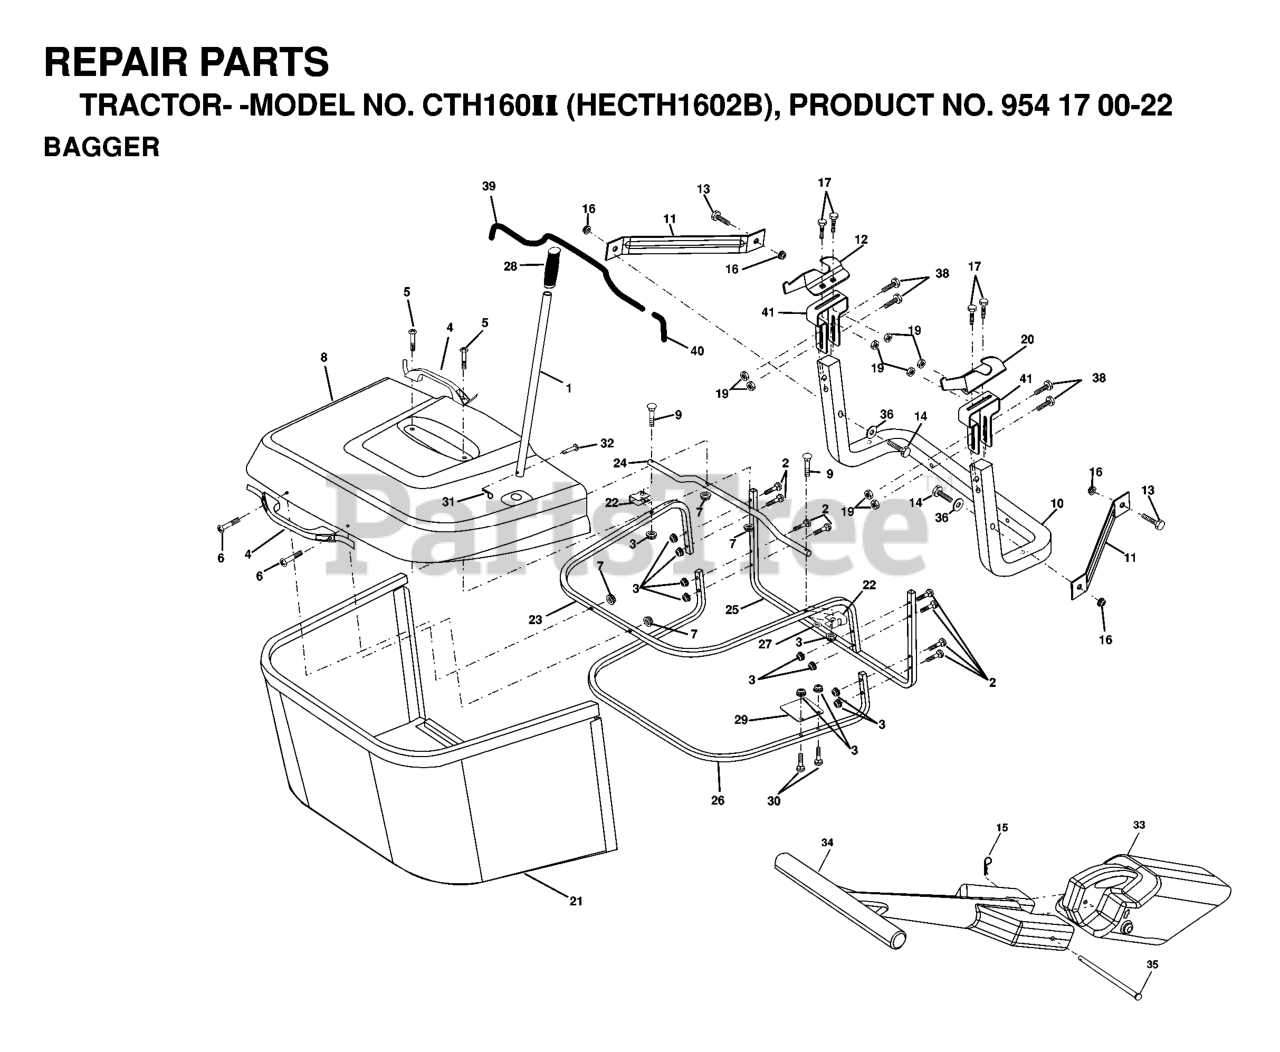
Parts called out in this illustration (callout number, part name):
1	TUBE HANDLE
2	Bolt Carriage 1/4-20 x 2.0 Gr.5
3	NUT T
4	HANDLE.BAGGER.W/LVRS.BLK.CRD
5	SCREW.PAN.HEAD
6	REPL BY 532 75 00-29
8	COVER
9	Bolt Carriage 1/4-20 x 2.25d x Gr.5
10	TUBE
11	BRACKET.SUPPORT.UPPER.BAG.CRD
14	Bolt Hex 3/8-16 x 2-1/2 Gr. 5
15	RETAINER-SPRNG RB
16	NUT LOCK FLG 3/8-16 UNC
17	RP BOLT 5/16-18 X3/4 ZN/YEL GR
18	WASHER M
19	NUT.71038.31-18.HEX.NYLOCK
20	BRACKET
21	BAG
22	BRKT.SIDE.BAG.CRD
23	TUBE.UPPER.BAG.CRD
24	TUBE.PIVOT.BAG.CRD.BLACK
26	TUBE.LOWER.BAG.CRD
28	GRIP.HANDLE.BLACK
30	Bolt Carriage 1/4-20 x 1 Gr.5
31	RETAINER M
32	RIVET,DRILLED
33	MULCH PLUG, CTH150
34	HANDLE.MULCHER.92.CRD (2 2)
36	WASHER
38	BOLT.5/16-18X2.5
39	TRIM
40	TRIM
41	BRKT.VERT.ADJ.BAGGER.CRD
